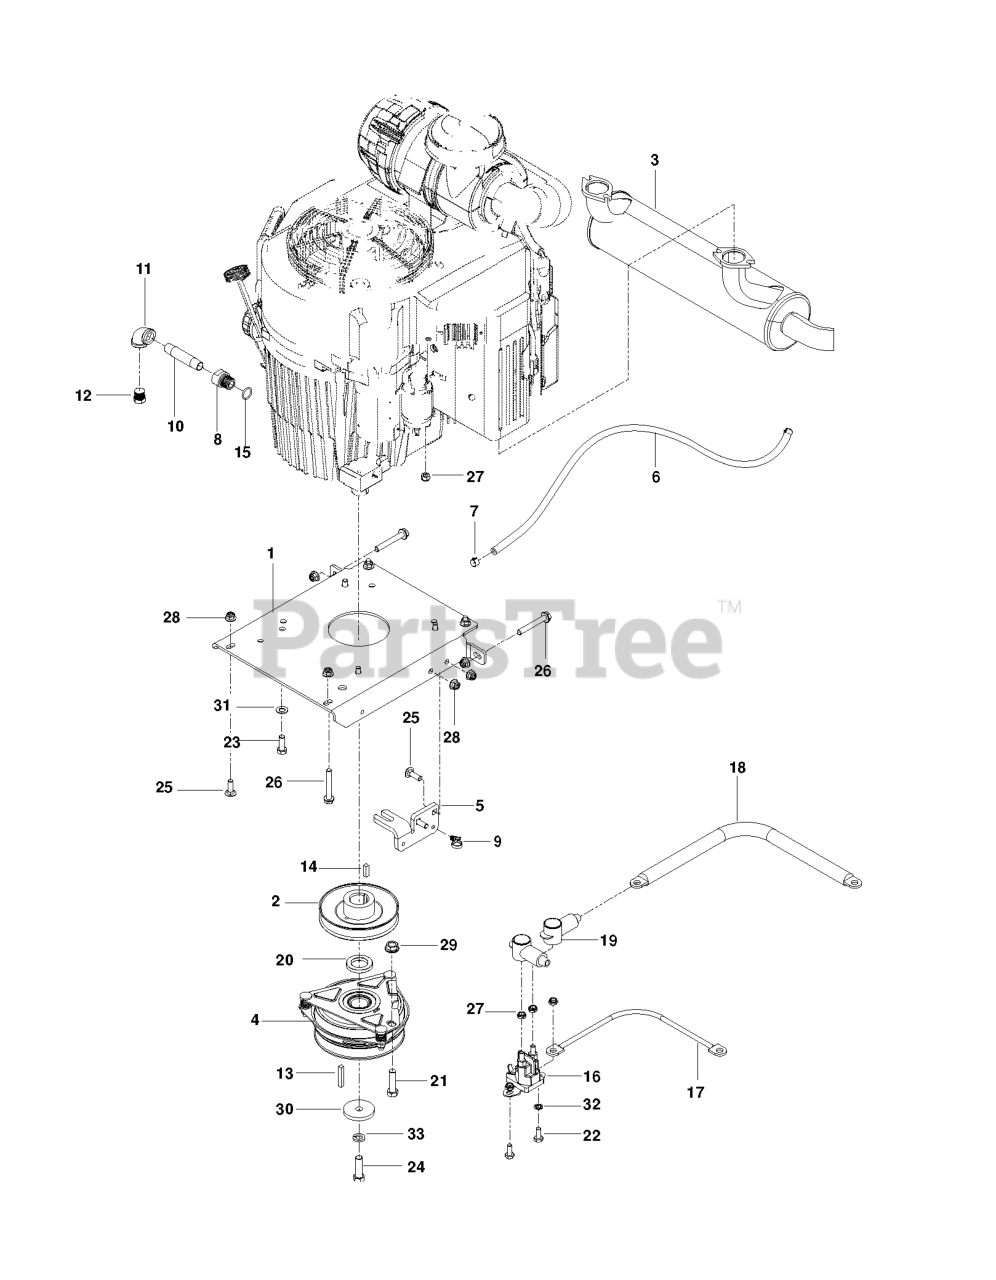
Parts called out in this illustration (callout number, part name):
1	PLATE.ENGINE.BLACK
2	PULLEY, ENGINE
3	MUFFLER.26HP.KAW.FX651V-730V
4	CLUTCH, 150 FT/LBS
5	STOP, CLUTCH, OGURA
6	FUEL LINE 18"
7	HOSE CLAMP
8	ADAPTER, OIL DRAIN
9	TIE WRAP, 8-3/8", W/CLIP
10	PIPE NIPPLE 3/8 X 3
11	90 DEG.ELBOW 3/8NPT
12	PLUG, DRAIN 3/8 NPTF
13	KEY 1/4 SQ X 2
14	KEY 1/4 SQ X 1.0
17	GROUND WIRE (KAW)
18	CABLE POSITIVE
20	SPACER, .25 X 1.135 I.D.
21	HCS 7/16-14 X 1-1/4 GR 5 ZD
22	HCS 1/4C X 5/8
23	HCS 3/8-16X1.GRD.5.ZD
24	HCS 7/16F X 1 1/2
25	RHSNB 5/16C X 1
26	HHFS 5/16-18 X 2.25 GD 5
27	JAM NUT 1/4C (2 2 PW01)
28	5/16-18 NYLOC FLANGE NUT
29	NUT 7/16C WHIZ
30	BLADE WASHER
31	WASHER, 3/8 DISC SPRING SPEC
32	WASHER 1/4 INT TOOTH
33	WASHER 7/16 LOCK
